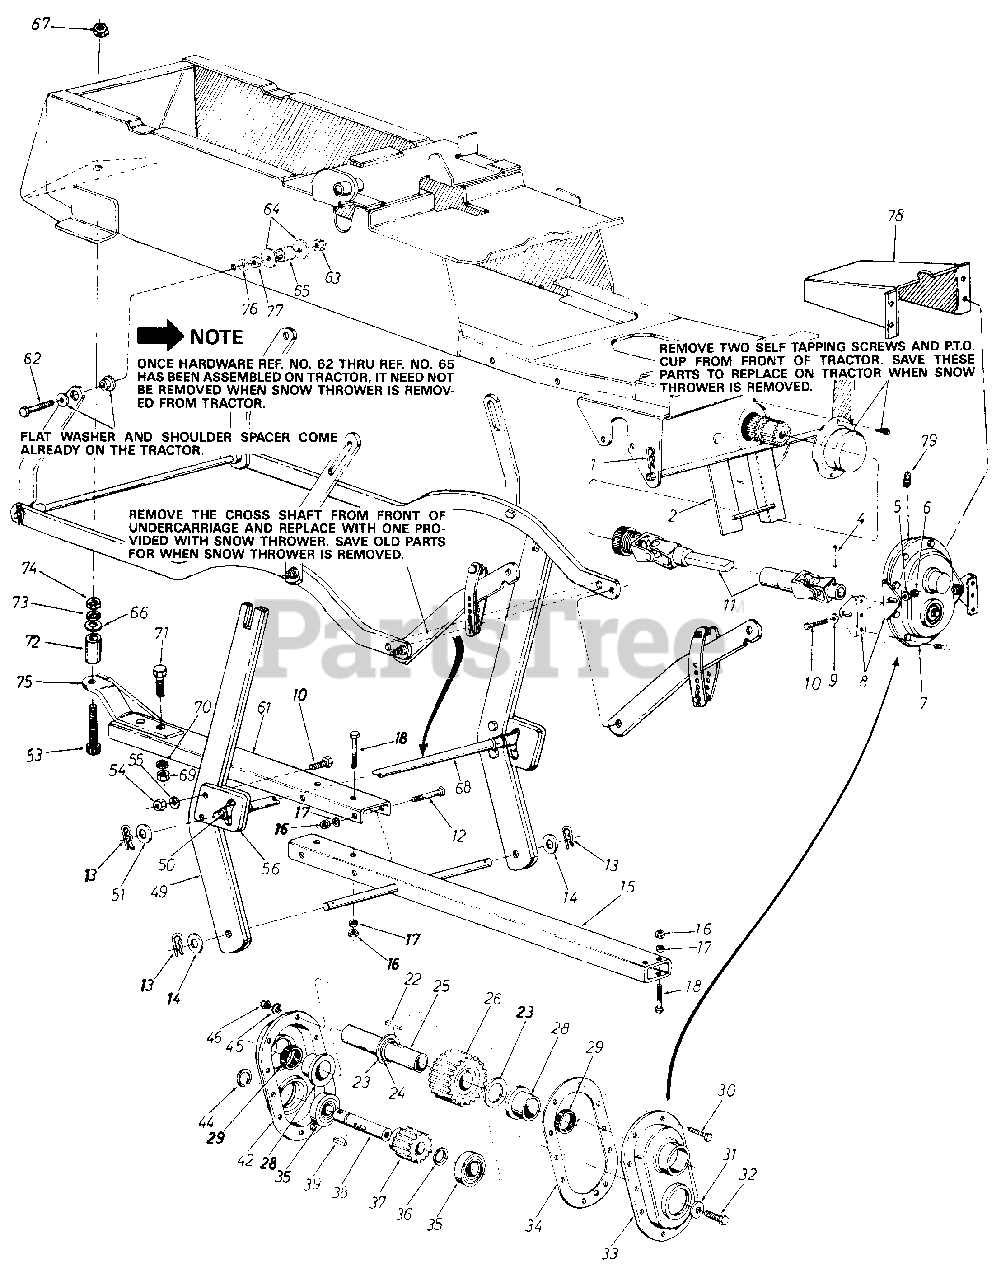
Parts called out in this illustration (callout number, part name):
1	Intern. Cotter Pin 3/4" Dia.
2	Guide Bracket Ass'y.
4	Roll Pin Spirol 5/16" Dia. x 2.5" Lg.
5	Belleville Wash. .341" I.D. x .88" O.D.
6	Hex Nut 5/16-18 Thd.*
7	Gear Box Ass'y. Comp.
8	Gear Box Support Brkt.
9	Belleville Wash. .341" I.D. x .88" O.D.
10	Hex Bolt 5/16-18 x 1.25" Lg.(Grade 5)
11	Universal Drive Shaft Ass'y.
12	Hex Bolt 3/8-24 x 4.50" Lg.*
13	Hair Pin Cotter
14	Fl.-Wash. .75" I.D. x 1.5" O.D.
15	Lift Shaft Ass'y.
16	Hex Ins. Jam L.-Nut 3/8-24 Thd.
17	L.-Wash. 3/8" I.D.*
18	Hex Bolt 3/8-24 x 2.75" Lg.
22	Hi-Pro Key 1/4" x 7/8" Dia.
23	Fl.-Wash. 1.31" I.D. x 2.00" O.D. x .060
24	Snap Ring for 1.25" Dia. Shaft
25	Gear Shaft 1.25" Dia. x 6.0" Lg.
26	28 Teeth Spur Gear
28	Flange Bearing 1.25" I.D. x 1.75" O.D.
29	Oil Seal 1.25" I.D. x 1.75" O.D. x .26
30	Hex Bolt 1/4-28 x .88" Lg.
31	Fl.-Wash. .40" I.D. x 1.25" O.D. x .160
32	Hex L.-Bolt 3/8-24 x 1.00" Lg.
33	Gear Housing Half-L.H.
34	Gasket
35	Ball Bearing 1.00" I.D. x 2.00" O.D.
36	Fl.-Wash. 1.03" I.D. x 1.63" x .090
37	15 Teeth Spur Gear
38	Input Shaft
39	Woodruff Key 1/4" x 3/4" Dia.
42	Gear Housing Half-R.H.
44	Snap Ring for 1.00" Dia. Shaft
45	Spring Wash. 1/4" I.D.
46	Hex Nut 1/4-28 Thd.
51	Fl.-Wash. .62" I.D. x 1.12" O.D.
53	Hex Bolt 5/8-11 x 4.00" Lg.*
54	Hex Nut 5/16-18 Thd.*
55	L.-Wash. 5/16" I.D.*
62	Hex Bolt 3/8-24 x 2.50" Lg.(Grade 5)
63	Hex Jam L.-Nut 3/8-24 Thd.
64	Fl.-Wash. .375" I.D. x 1.00" O.D. x .135"
65	Spacer.375" I.D. x .625" O.D. x .445
66	Fl.-Wash. .62" I.D. x 1.12" O.D.
67	Hex Jam L.-Nut 5/8-11 Thd.
68	Cross Shaft Ass'y.
69	Hex Nut 1/2-13 Thd.*
70	L.-Wash. 1/2" I.D.*
71	Hex Bolt 1/2-13 x 1.25" Lg.
72	Spacer .65" I.D. x 2.12" Lg.
73	L.-Wash. 5/8" I.D.*
74	Hex Jam Nut 5/8-11 Thd.
77	Hex Nut 3/8-24 Thd.*
78	Drive Shaft Cover
79	Grease Fitting
